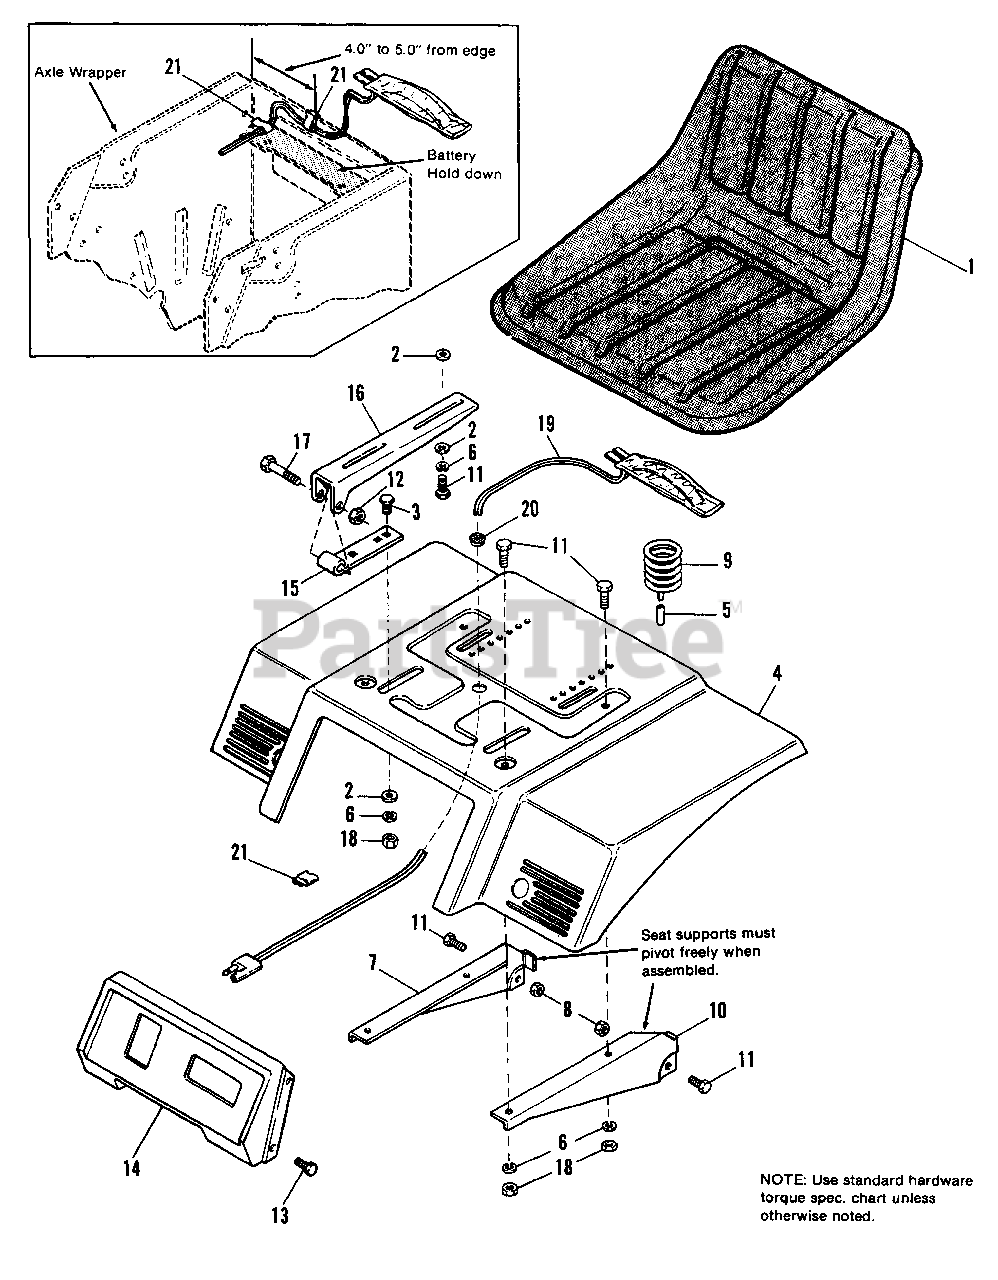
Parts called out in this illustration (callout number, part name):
2	WASHER, Plain, 5/16
3	CAPSCREW, Hex, 5/16-18 x 1.0
4	DECK, Seat
5	COVER, Wire
6	LOCKWASHER, 5/16
7	SUPPORT, Seat, R.H.
8	LOCKNUT, Hex, 5/16-18
9	SPRING, Seat
10	SUPPORT, Seat, L.H.
11	CAPSCREW, Hex, 5/16-18 x 3/4
12	LOCKNUT, Hex, 3/8-16
13	SCREW, Hex, Taptite, 1/4-20 x 1/2
14	PANEL, Shift
15	HINGE, Lower
16	HINGE, Upper
17	CAPSCREW, Hex, 3/8-16 x 2
18	NUT, Hex 5/16-18
19	SWITCH, Seat
20	BUSHING, Universal
